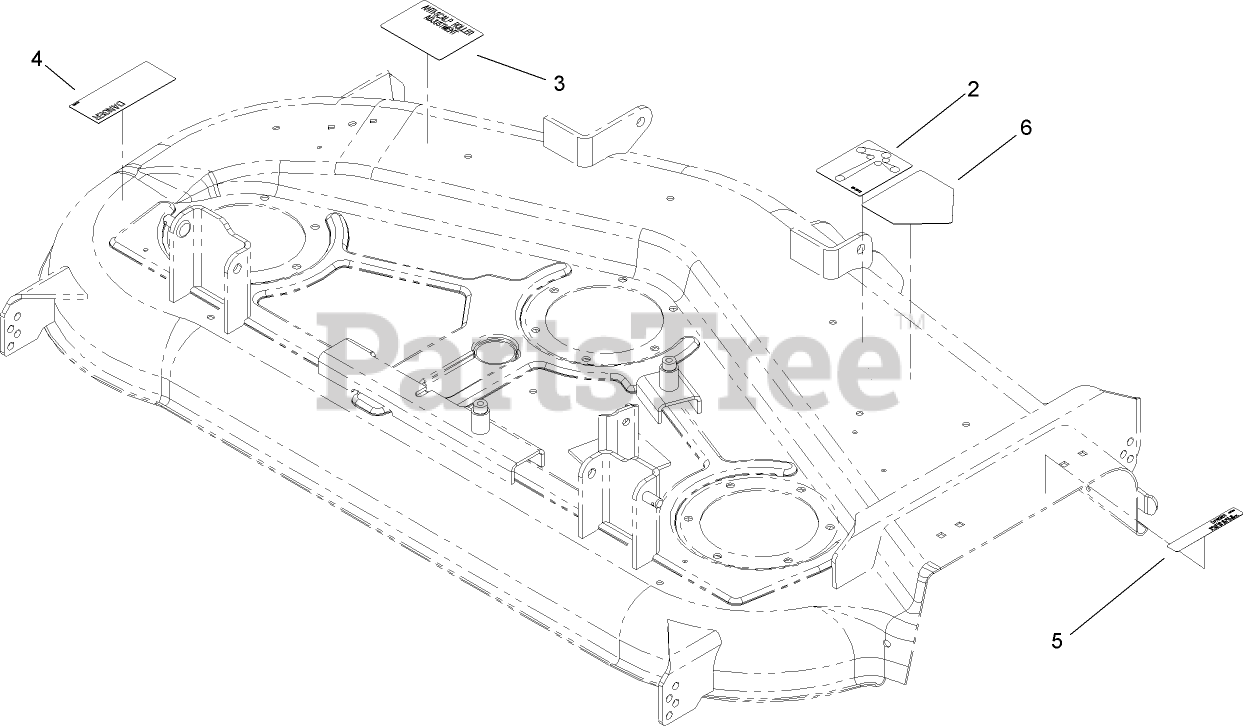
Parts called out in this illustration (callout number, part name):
2	DECAL-ROUTING, BELT
3	DECAL-WHEEL, GAGE
4	DECAL-DANGER
5	DECAL-CAUTION
6	DECAL-DANGER
